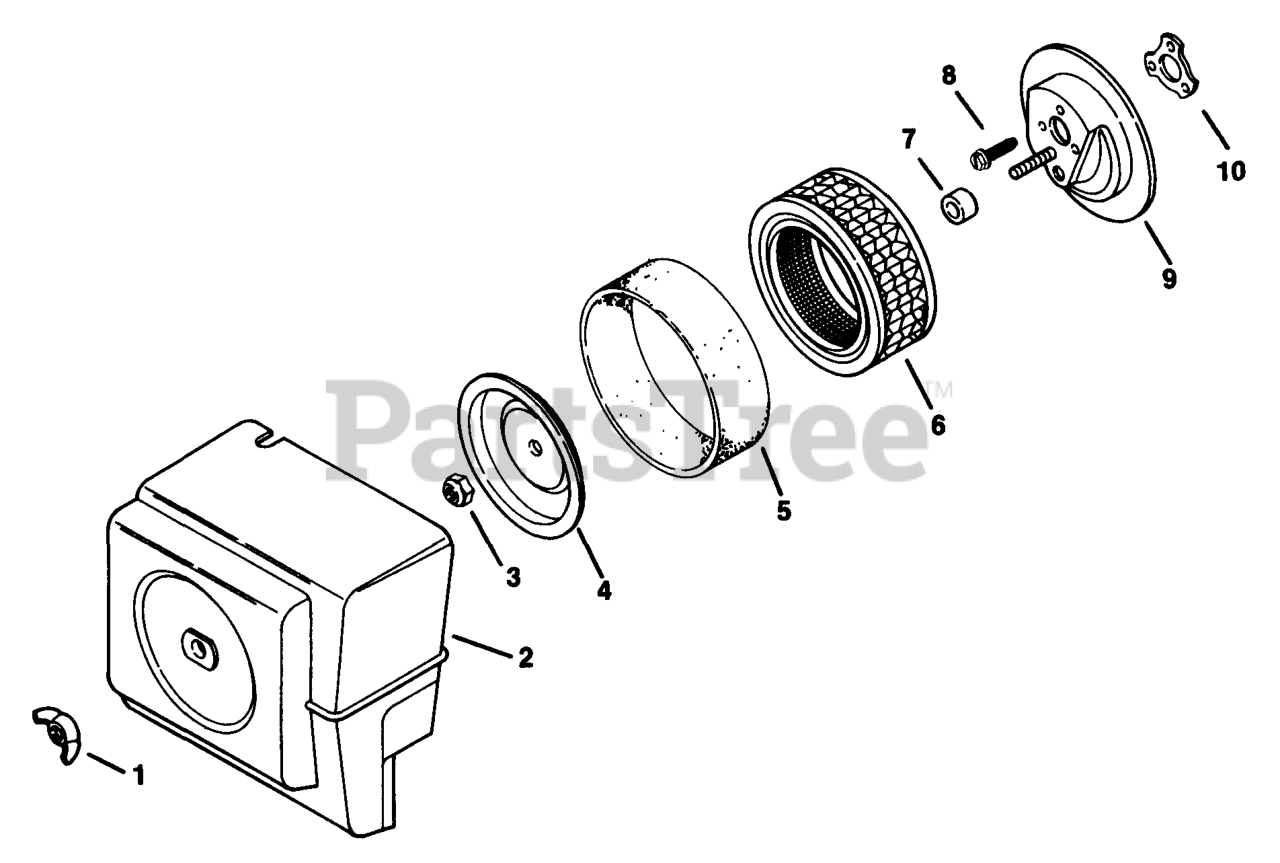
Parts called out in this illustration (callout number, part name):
1	NUT, WING 1/4-20 USE 25 100 15-S
2	COVER - USE 41 096 29
3	NUT, LOCK 1/4-20
4	COVER, INNER AIR CLEANER
6	AIR FILTER/PRE-CLEANER KIT USE 25 883 03-S1
8	SCREW, WASHER HD TAP #8-32X3/8" USE 25 086 99-S
9	KIT - USE 41 743 02
10	GASKET - USE 41 041 11
